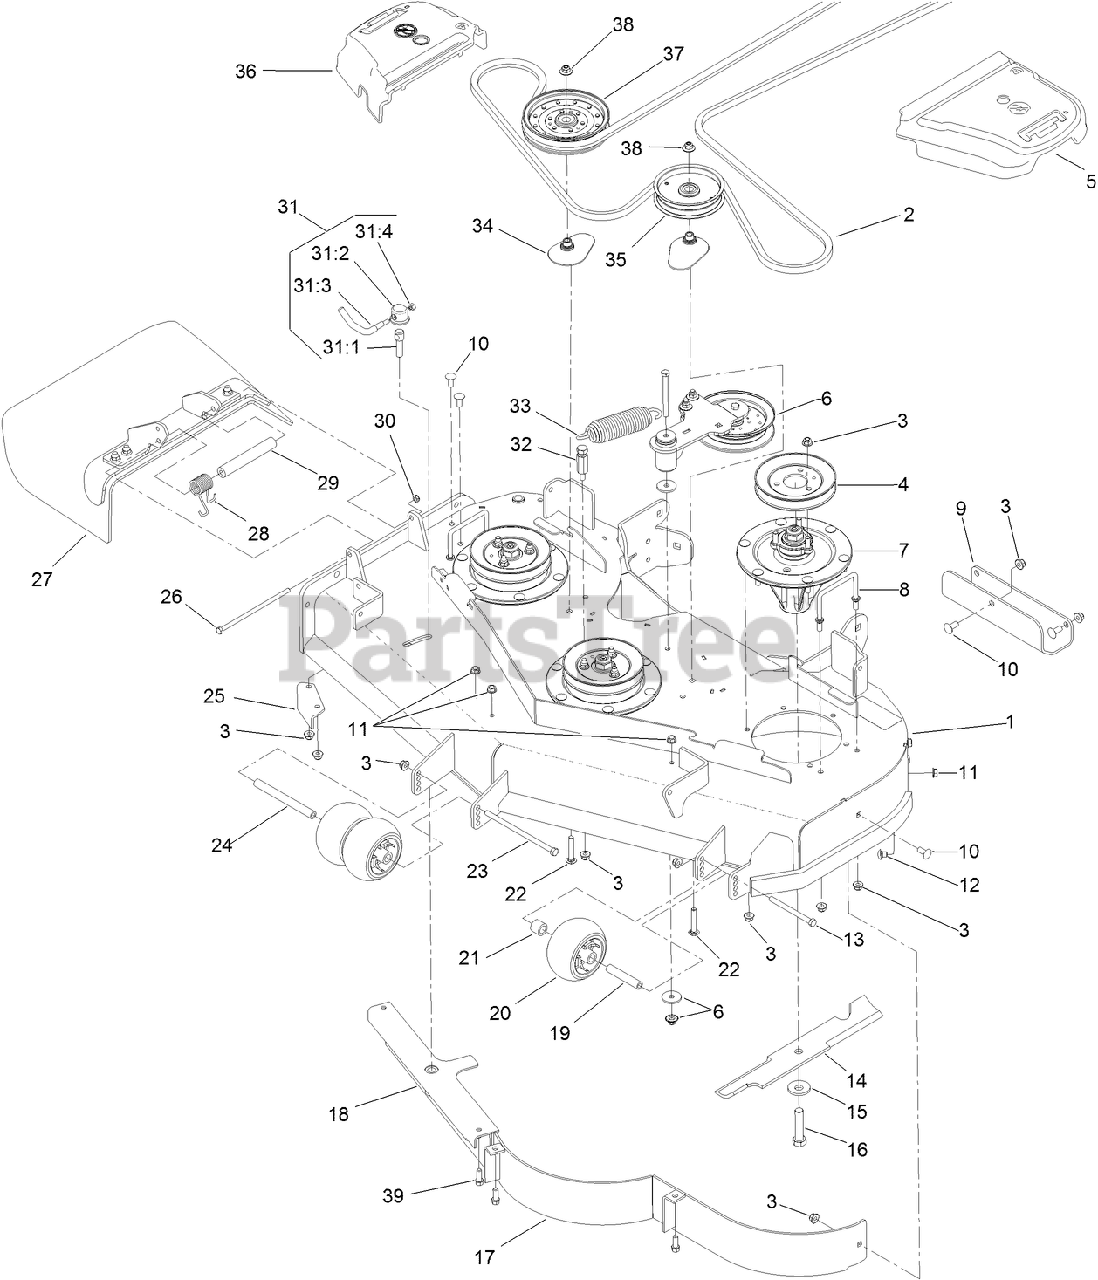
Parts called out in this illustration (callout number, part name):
1	DECK DECAL ASM
2	BELT-V
3	NUT-HF, NI
4	PULLEY
5	COVER-BELT, LH
6	IDLER ARM ASM
7	SPINDLE ASM
8	WIREFORM-COVER
9	PLATE-SKID
10	SCREW-CARR
11	NUT-HHF, WHIZ
12	SCREW-CARR
13	SCREW-HH
14	BLADE-16.5 INCH (HIGH FLOW)
15	Washer-Blade Bolt, Heavy
16	SCREW-BLADE
18	BAFFLE
19	TUBE-SPANNER
20	ROLLER-SCALP, ANTI
21	TUBE-SPACER
22	BOLT-CARR, SHORT NECK
23	SCREW-HH
24	SPACER-WHEEL
25	BAFFLE-DISCHARGE
26	SCREW-HH
27	RUBBER DEFLECTOR ASM
28	SPRING-TORSION
29	SPACER
30	NUT-LOCK, NI
31	LEVER ASM
31:1	Screw-Lock
31:2	CAP-LOCK
31:3	Lever-Lock
31:4	NUT-LOCK, NI
32	ANCHOR-SPRING, TALL
33	SPRING-EXTENSION
34	SPACER-PULLEY
35	PULLEY-IDLER, FLAT
36	COVER-BELT, RH
37	PULLEY-IDLER, FLAT
38	NUT-FLANGE, NI
39	SCREW-HWH
